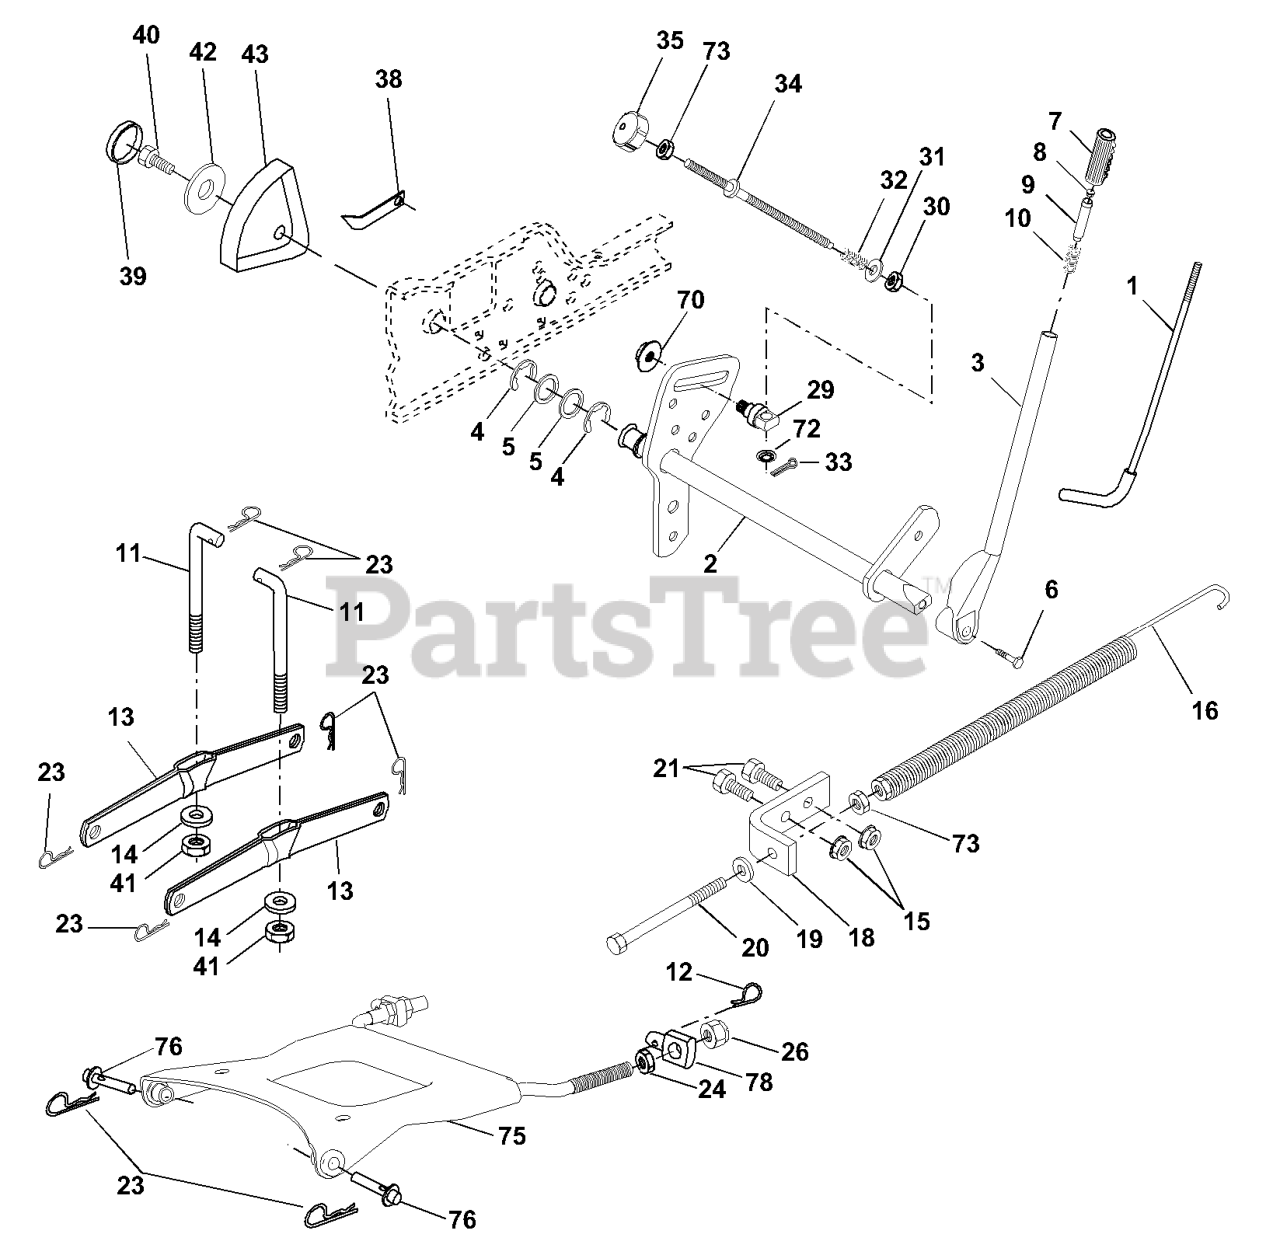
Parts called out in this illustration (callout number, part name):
1	LEVER ROD LT
2	SHAFT ASM, LIFT
3	LEVER ASSY-LIFT RH
5	Washer 29/32 x 1-1/4 x 16 Ga.
6	Bolt, Fin Hex 3/8-16 x 1-1/2
7	GRIP HANDLE
8	PLUNGER BUT KIT
9	PLUNGER BUT KIT
10	SPRING**
11	LINK LIFT
12	SPRING RETAINER
13	ARM.REAR.SUSPENSION
14	BEARING.PIVOT.LIFT
16	LIFT SPRING
19	WASHER
21	BOLT
23	RETAINER-SPRNG RB
24	NUT.HEX.JAM.1/2-13
26	NUT.LK.W/WSH.1/2.
32	SPRING.COMP.INF.H
33	COTTER PIN
34	ROD.LIFT.ADJUSTABLE
35	KNOB INF 3/8-16
38	POINTER, HEIGHT INDICATOR(2 2)
40	SCREW 5/16-18X1
41	NUT CROWNLOCK 3/8-24
43	HEIGHT INDICATOR
70	NUT
72	NUT PUSH M
73	NUT
75	PLATE ASM SUSP FRONT
76	PIN.FLANGE
